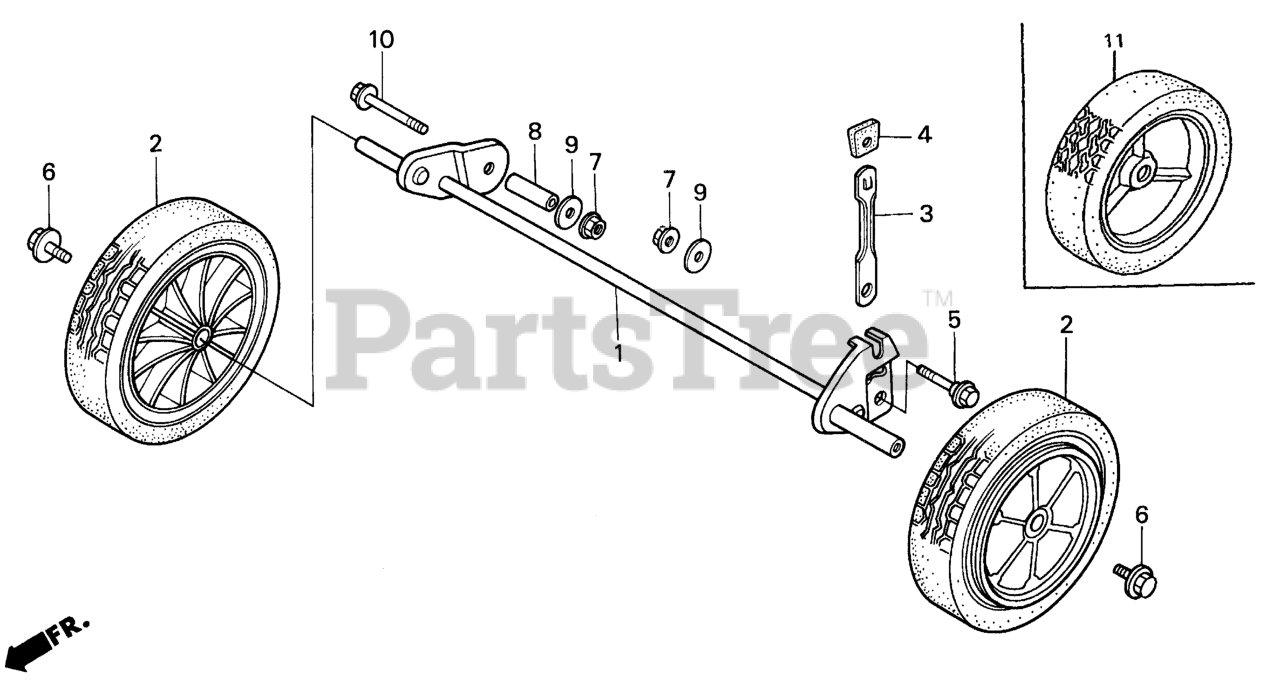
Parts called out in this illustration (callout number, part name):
1	SHAFT, FR. AXLE (NOT AVAILABLE)
2	WHEEL (7X1.5)
2	WHEEL (7")
3	PLATE, FR. ADJUSTING (NOT AVAILABLE)
4	GRIP, ADJUSTER
5	BOLT, ADJUSTING CENTER
6	BOLT, WHEEL
7	NUT, FLANGE (8MM)
8	COLLAR A, ADJUSTING CENTER
9	WASHER, PLAIN (8MM)
10	BOLT, FLANGE (8X50)
11	WHEEL (7") *NH31* (MCKINLEY WHITE)
